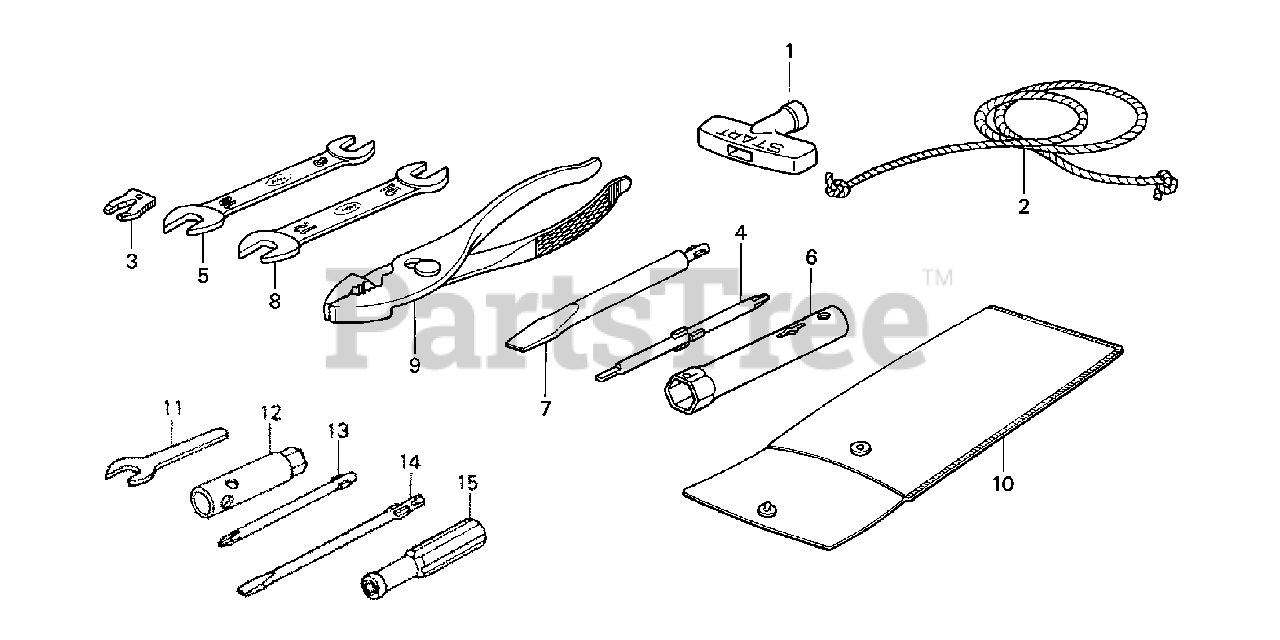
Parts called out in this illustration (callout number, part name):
1	KNOB, RECOIL STARTER
2	ROPE, RECOIL STARTER (#5X58")
3	CLIP, EMERGENCY LOCK
4	DRIVER
5	SPANNER (8X10)
6	WRENCH, SPARK PLUG
7	SCREWDRIVER, CHECK BOLT
8	WRENCH (10X12) (OPEN END)
9	PLIERS (135MM)
10	BAG, TOOL (160MM)
11	WRENCH (8MM) (OPEN END) (NOT AVAILABLE)
12	WRENCH, BOX (10MM)
13	SCREWDRIVER 1, PHILLIPS (NO.2)
14	SCREWDRIVER 3, STRAIGHT SLOT (NO.2)
15	GRIP
